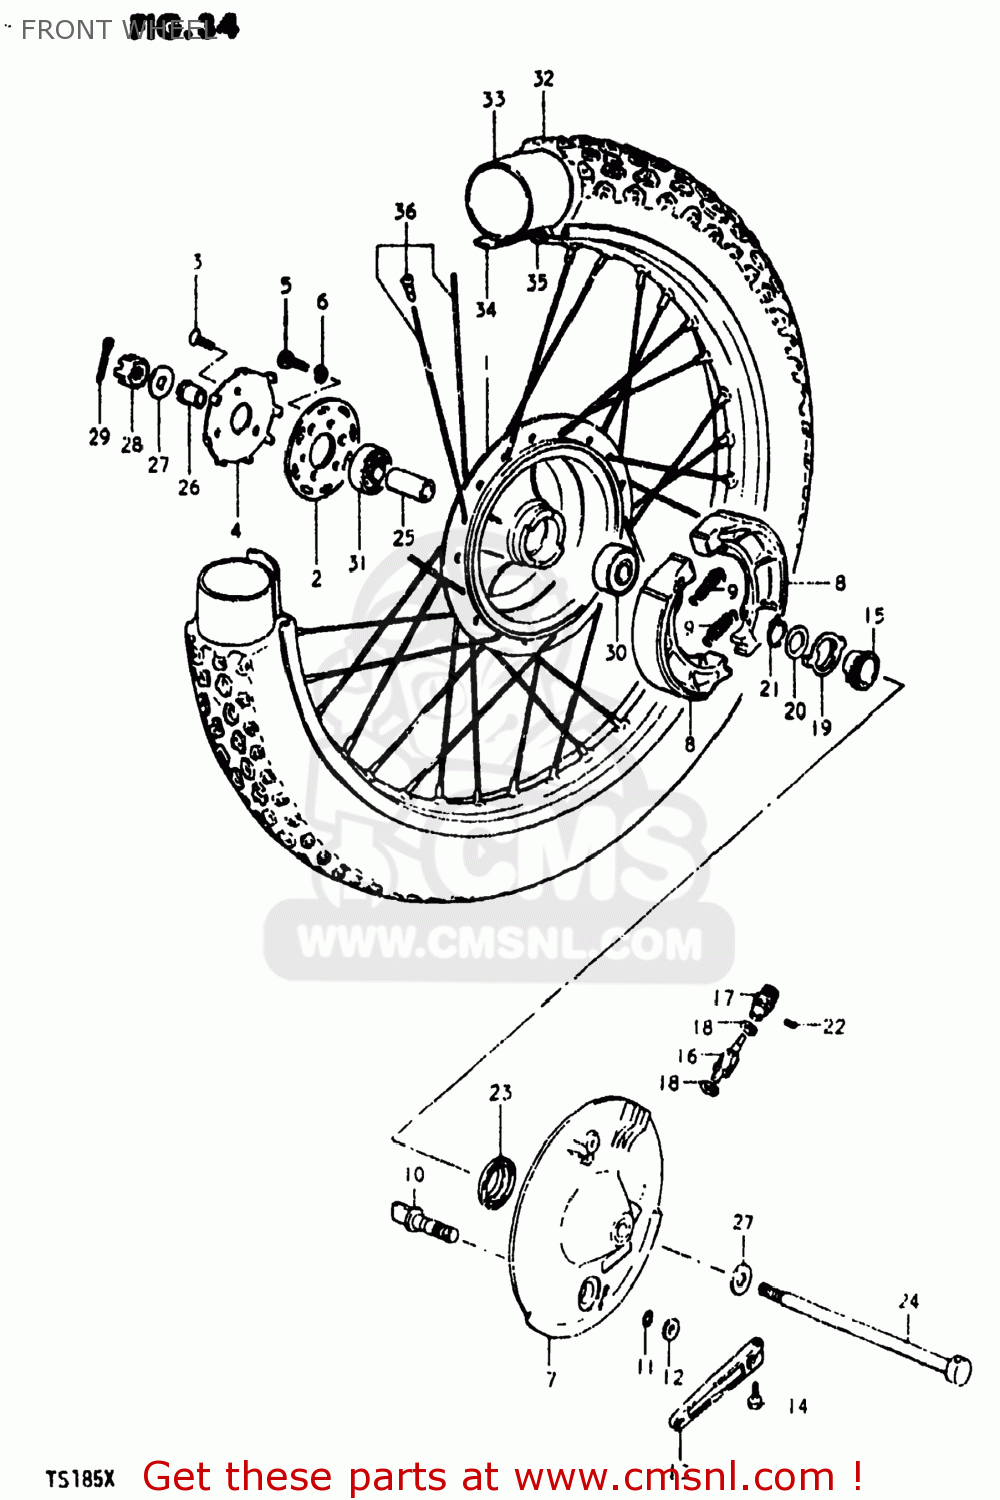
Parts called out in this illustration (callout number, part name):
1	HUB,FR WHEEL
2	FLANGE,FR HUB,R
3	SCREW
4	RETAINER,FR HUB BEARING,R
5	BOLT, UPPER
6	LOCK WASHER
7	PANEL,FRONT HUB
8	SHOE,BRAKE
9	SPRING(L:34)
10	CAM,FRONT BRAKE
11	O-RING (D:2.4 ID:13.8)
12	WASHER (14.5X22X1.6)
13	LEVER,FRONT BRAKE CAM
14	BOLT
15	GEAR,SPEEDOMETER
16	PINION,SPEEDOMETER
17	BUSH,METER GEAR OUTER
18	WASHER (5.1X9X0.4)
19	DRIVER,SPEEDOMETER GEAR
20	WASHER(18.5X24X1)
21	CIRCLIP
22	SCREW
23	OIL SEAL (43X58X7)
24	AXLE,FRONT
25	SPACER (12.6X19X52)
26	SPACER,FR AXLE,R
27	WASHER
28	NUT 12MM
29	COTTER PIN
30	BEARING
31	BEARING, RH
32	TIRE,FR
33	TUBE
34	PROTECTOR,WHEEL,INNER
35	RIM,FR WHEEL(1.60X21)
36	SPOKE SET,FR
